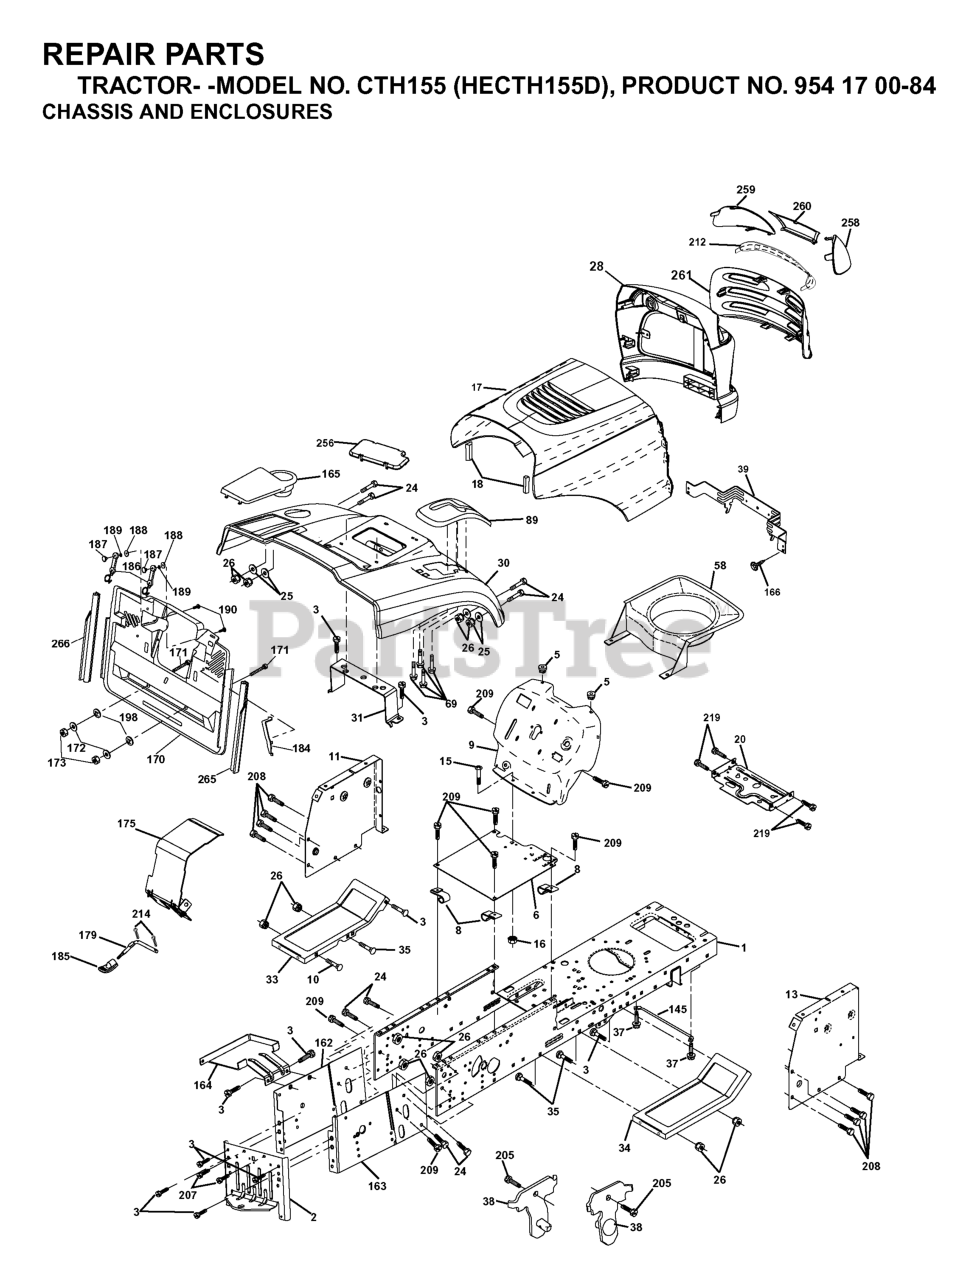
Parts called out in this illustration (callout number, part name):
2	DRAWBAR
3	SCREW 3/8-16X3/4
5	BUMPER.RUBBER.HOOD
6	PLATE
8	CLIP,INSULATOR
10	BOLT D
11	PANEL.DASH.LH.LTX
13	PANEL ASM, DASH RH
15	Screw, Machine, Truss Head 5/16-18 UNC x 3/4
16	NUT
17	HOOD
18	BUMPER.HOOD.LARGE.1.75"
20	PLATE MTG.BATTERY/FUEL TANK
25	WASHER
26	NUT
31	BRACKET SUPPORT FENDER
33	FOOTREST PNT LH
34	FOOTREST PNT RH
37	Screw 5/16-18 x 1/2 Hex, Self Tapping 5/16-18 x 1/2
38	BRACKET ASM PIVOT MOWER REAR
39	BRACKET PIVOT LASER
58	AIR DUCT P/L/LT
69	SCREW.HI-LO.CONSOLE
89	COVER.BATTERY.CRD.GREY
145	ROD PIVOT CHASSIS/HOOD
162	BRACKET
163	BRACKET EXTEN CHASSIS RH CRD
165	RP.COVER.BATTERY.CRD.GREY
166	SCREW
172	WASHER
184	BRACKET.ACTUATOR.BAGGER.SRD
186	LATCH ASSY
187	WELDNUT
189	LOCKWASHER #10
190	SCREW
207	SCREW, 5/16-18 X 1/2
208	SCREW 3/8-16X1/2
209	SCREW, 3/8-16X3/4
212	INSERT.LENS.REFLECTIVE
214	RETAINER M
219	SCREW
256	COVER FENDER CRD
258	LENS LH
259	LENS LH
260	COVER.LENS.HUSQ.LASER
265	SEALING
266	SEALING
